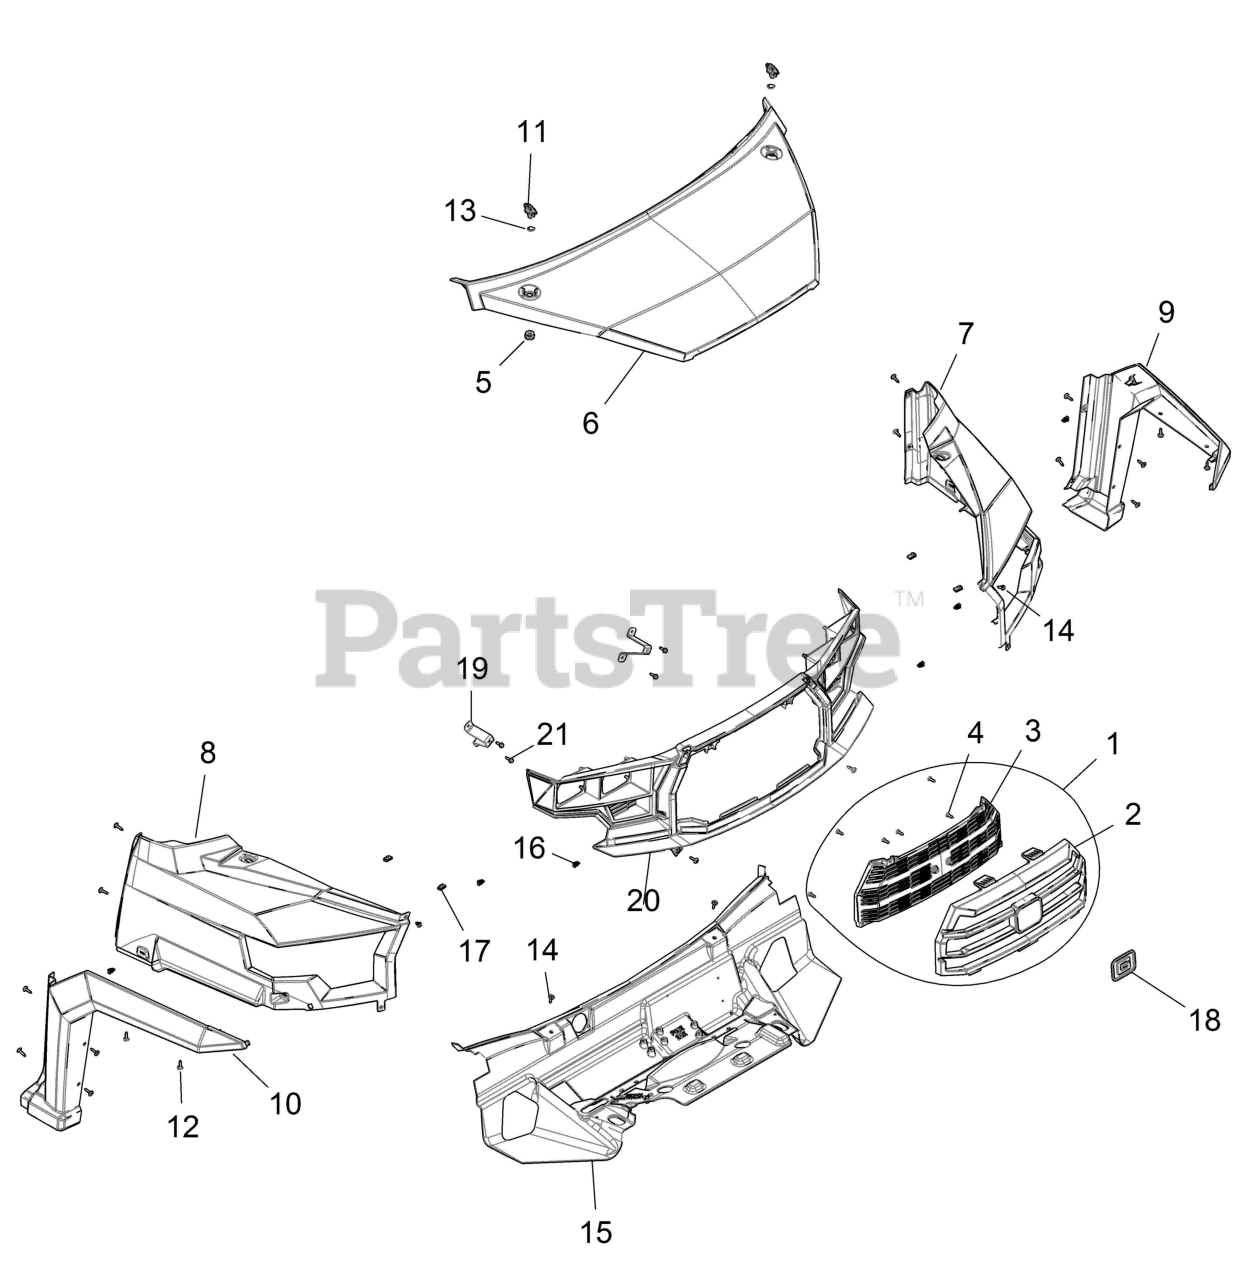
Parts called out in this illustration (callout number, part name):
1	ASM., GRILL, GRAVELY
2	GRILL, FRONT, UPPER, BLACK
3	GRILL, UPPER, TRIM
4	SCR-TXPH-#14 X .75 HI-LO RIE
5	GROMMET-LATCH
6	HOOD-ARIENS,INDY RED
7	FENDER-FRONT,LH,ARIENS,I RED
8	FENDER-FRONT,RH,ARIENS,I RED
9	FLARE, FENDER, FRONT LH
10	FLARE, FENDER, FRONT RH
11	LATCH, 1/4 TURN
12	SCR-TXTH-M6X1.0X25 RIE
14	RIVET-TUFLOK,.315-.325X.787 (5
15	LINER-HOOD,BLK
16	CLIP, DASH TRIM METAL
17	CLIP-U SPEED NUT
19	BRKT-FASCIA MOUNT
20	BEZEL-HEADLIGHT
21	SCR-M6X1.0X20,HXHD,FLG,TDFM,BL
